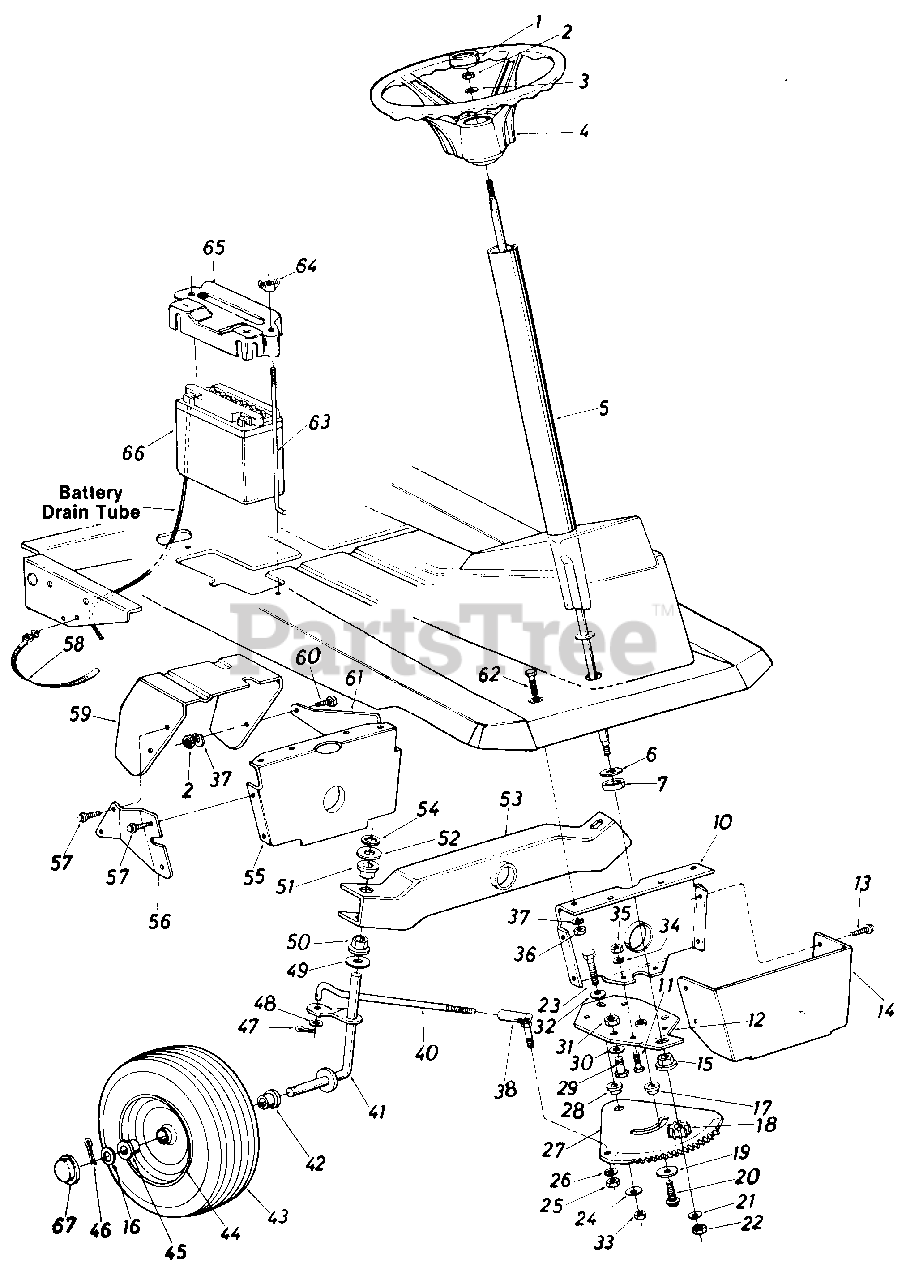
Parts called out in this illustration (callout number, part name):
1	Steering Wheel Cap
2	Hex Nut 5/16-18 Thd.
3	Bell-Wash. .345" I.D. x .88" O.D.
4	Steering Wheel Ass'y.
5	Steering Shaft Ass'y.
6	Fl-Wash. .62" I.D. x 1.50" O.D.
7	Spacer (Plastic)
10	Pivot Bar Bracket
11	Hex Bolt 5/16-18 x .75" Lg.
12	Steering Gear Support Brk't.
13	Hex Wash. Hd. AB-Tap Scr. 1/4 x .62" Lg.
16	Fl-Wash. .64" I.D. x 1.62 O.D.
17	Shoulder Spacer .622 Dia. x .21 8
18	Steering Pinion Gear
19	Fl-Wash. .385" I.D. x 1.38" O.D.
20	Hex Wash. Hd. Self-Tap Scr. 3/8-16 x 1.25" Lg.
21	Bell-Wash. .345" I.D. x .88" O.D.
22	Hex Nut 5/16-24 Thd.
23	Hex Bolt 3/8-24 x 1.25" Lg. Grade 5
24	Fl-Wash. .385" I.D. x 1.38" O.D.
25	Hex Nut 3/8-24 Thd.
26	L-Wash. 3/8" I.D.
27	Steering Gear Segment
28	Shoulder Spacer .622" Dia. x .21 8
29	Hex Bolt (Nylon) 1/2-13 x .75" Lg.
30	Fl-Wash. .530" I.D. x .930" O.D.
31	Hex Nut 1/2-13 Thd.
32	Bell-Wash. .385" I.D. x .88" O.D.
33	Hex Nut 3/8-24 Thd.
34	L-Wash. 5/16" I.D.
35	Hex Nut 5/16-18 Thd.*
36	Hex Nut 5/16-18 Thd.*
37	L-Wash. 5/16" I.D.*
38	Ball Joint Ass'y. 3/8-24 Thd.
40	Steering Tie Rod
41	Front Axle Ass'y. R.H.
42	Flange Bearing .632" I.D.
43	Front Wheel Ass'y. Comp.
44	Front Wheel Rim Only
45	Flange Bearing .632" I.D.
46	Cotter Pin 118" Dia. x 1.25" Lg.*
47	Cotter Pin 118" Dia. x 1.00" Lg.*
48	Fl-Wash. .385" I.D. x .87" O.D.
49	Fl-Wash. .635" I.D. x 1.12" O.D.
50	Hex Flange Bearing
51	Hex Flange Bearing
52	Fl-Wash. .635" I.D. x 1.12" O.D.
53	Pivot Bar Ass'y.
54	Speed Nut 5/8" I.D.
55	Pivot Bar Bracket
56	Bracket Reinforcement R.H.
57	Hex Wash. Hd. AB-Tap Scr. 1/4 x .62" Lg.
58	Cable Tie
59	Clutch-Brake Pedal Ass'y.
60	Hex Bolt 5/16-18 x .75" Lg.
61	Bracket Reinforcement
62	Hex Bolt 5/16-18 x .75" Lg.*
63	Battery Hold Down Rod
64	Wing Nut Solid 1/4-20 Thd.
65	Battery Cover
66	12V Battery
67	Plastic Hub Cap
